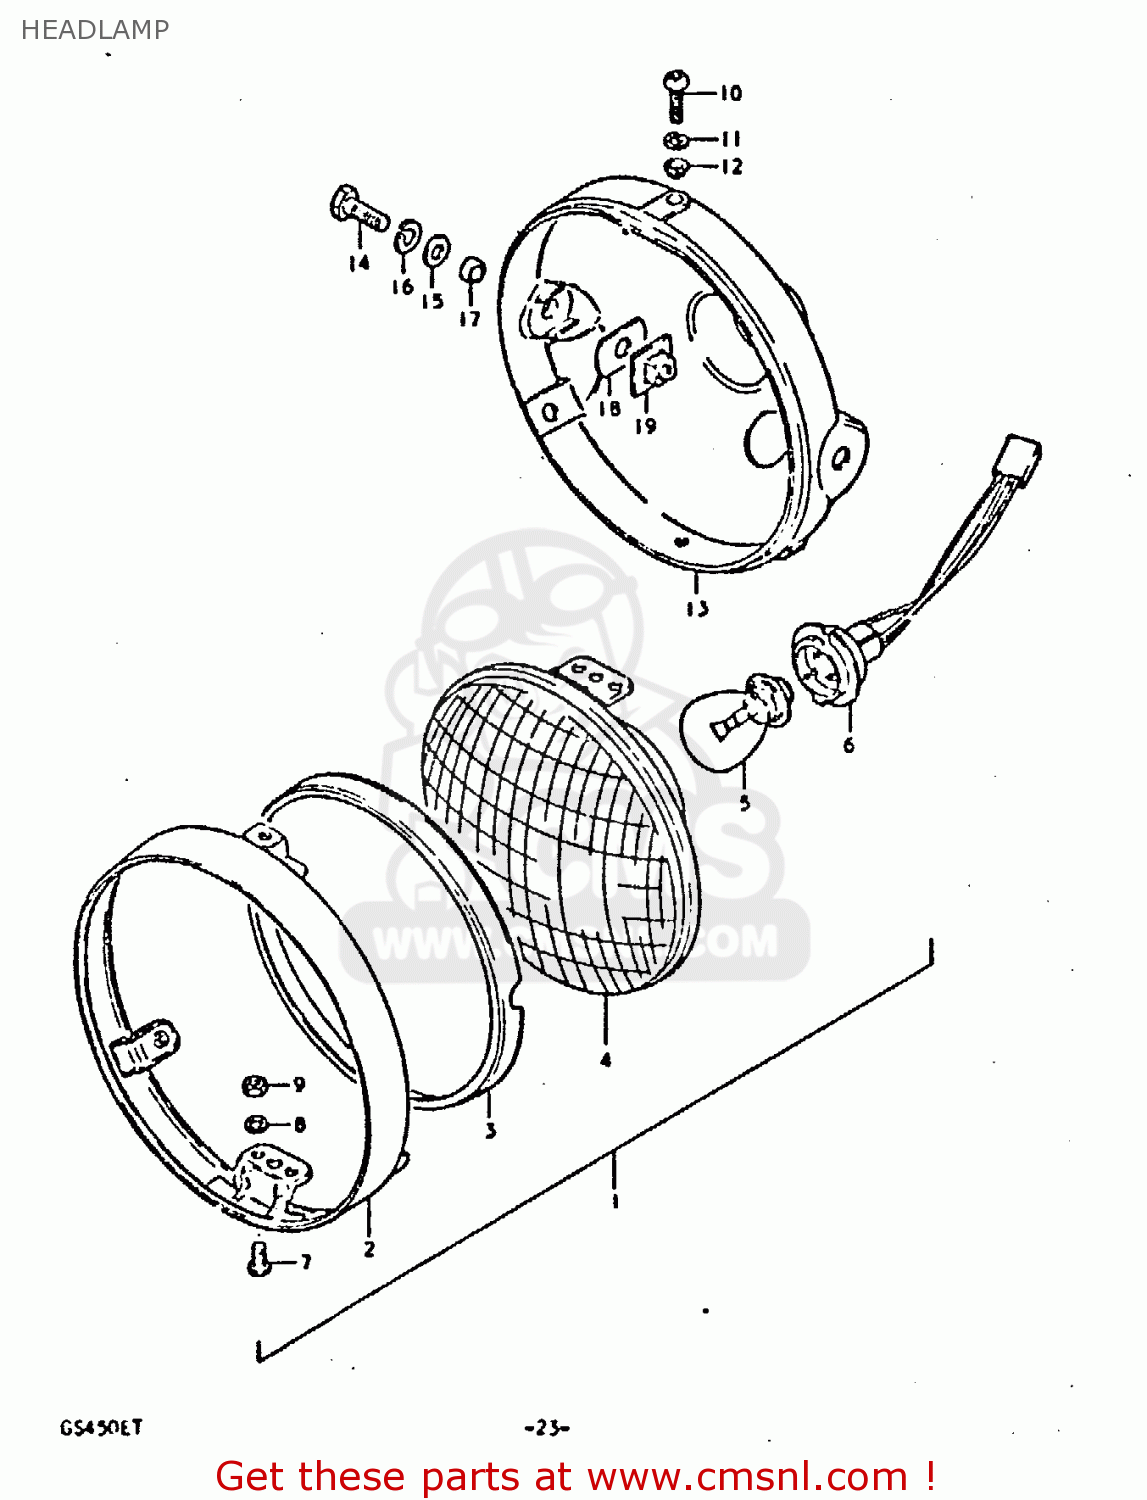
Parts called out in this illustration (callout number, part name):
1	HEADLAMP ASSY
2	RIM
3	RETAINER,HEADLAMP
4	UNIT
5	BULB
6	SOCKET
7	SCREW
8	LOCK WASHER
9	NUT
10	SCREW
11	WASHER,LOCK
12	WASHER
13	HOUSING,HEADLAMP(BLACK)
14	BOLT
15	WASHER
16	LOCK WASHER
17	SPACER (8.8X12X7)
18	CUSHION
19	PLATE,HEADLAMP HOUSING
